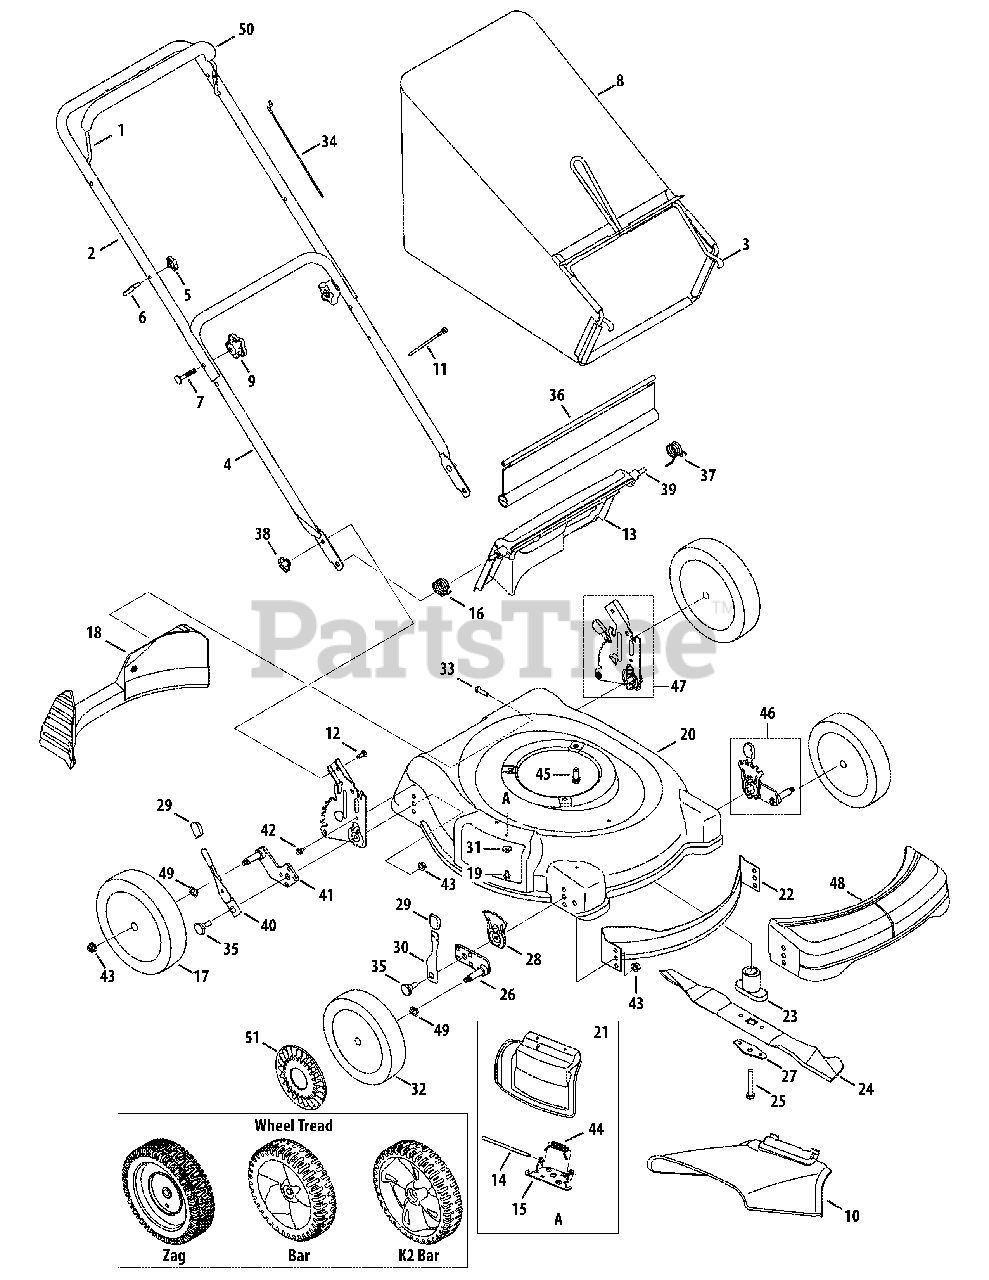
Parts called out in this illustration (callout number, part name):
5	Wing Nut
6	Rope Guide
7	Carriage Bolt, 5/16-18 x 2
8	Grass Bag - Black
8	Grass Bag - Yardman
8	Grass Bag - Gray
9	Hand Knob
10	Side Chute
11	Cable Tie
12	Carriage Bolt, 1/4-20
13	Rear Discharge Door
14	Hinge Pin
15	Deflector Chute Adapter
16	Torsion Spring - RH
17	Rear Wheel, 8 x 1.8, K2 Bar
17	Rear Wheel, 8 x 2.125, Zag
17	Rear Wheel, 8 x 1.8, Bar
17	Rear Wheel, 8 x 2.125, Zag BB
18	Rear Baffle
19	Screw, 1/4-20 x .500
22	Front Baffle
23	Blade Adaptor, #6 x 2.15
23	Blade Adaptor, 25mm x 2.15
24	Mulching Blade
25	Hex Screw, 3/8-24 x 2.5
26	Pivot Arm Assembly - RH 7'' Wheel
26	Pivot Arm Assembly - LH 7'' Wheel
26	Pivot Arm Assembly - RH 8'' Wheel'
26	Pivot Arm Assembly - LH 8'' Wheel
27	Blade Bell Support
28	Front Adjustment Plate
29	Adjustment Lever Knob
30	Spring Lever Assembly
31	Bell Washer
32	Front Wheel, 7 x 1.8, K2 Bar
32	Front Wheel, 8 x 2.125, Zag
32	Front Wheel, 7 x 1.8, Bar
32	Front Wheel, 8 x 2.125, Zag BB
33	Screw, 1/4-15 x 1.000
34	Control Cable 40''
34	Control Cable 53''
35	Shoulder Screw
36	Trailshield
37	Torsion Spring - LH
38	Wing Nut, 1/4-20
39	Rear Door Pivot Rod
40	Spring Lever
41	Pivot Arm Assembly - RH
41	Pivot Arm Assembly - LH
42	AB Screw
43	Flanged Lock Nut, 3/8-16
44	Torsion Spring
45	TT Sems Screw, 3/8-16 x 1.0
46	Height Adjustment Ass'y Front - LH 7'' Wheel
46	Height Adjustment Ass'y Front - RH 7'' Wheel
46	Height Adjustment Ass'y Front - LH 8'' Wheel
46	Height Adjustment Ass'y Front - RH 8'' Wheel
47	Rear Handle Bracket Assembly - LH
47	Rear Handle Bracket Assembly - RH
48	Front Cover
49	Wave Washer
50	Bail Cover - Black
50	Bail Cover - Gray
51	Hub Cap
